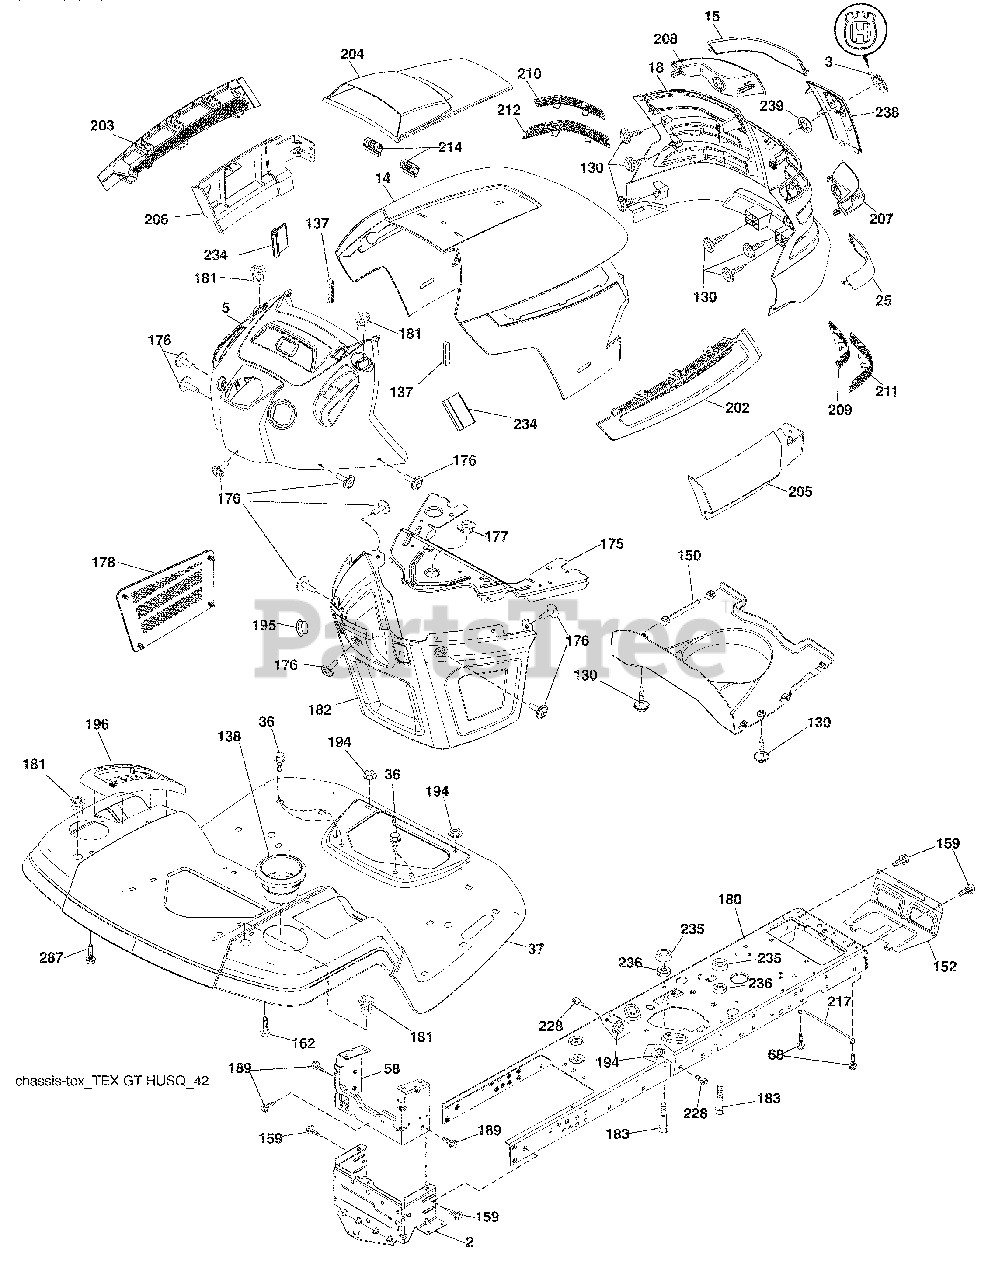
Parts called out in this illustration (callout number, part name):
2	Drawbar Lower
3	Logo
14	Hood
18	Grille/Lens Asm.
36	Screw 5/16-18 x 3/4
37	Fender
58	Drawbar Upper 2PC Sml. Fender
68	Screw Thdrol 5/16-18 x 1/2
130	Screw #10 x 0.750
137	Bumper Dash
138	Cupholder
152	Shield Browning
159	Screw Hex THDROL 3/8-16 x 3/4
175	Crossmember
176	Screw 10-24 x 5/8
177	Bushing Steering
178	Cargo Net Asm.
180	Chassis
181	Bushing Mtg. Fender Crgo
182	Dash Lower
183	Bolt Fin Hex 5/16-18 unc x 1-1/4
189	Screw 5/16-18 x 3/4
194	Nut Lock Hex Flange 5/16-18
195	Plug Hole Dash Lower
196	Console Asm. Deck Lift
202	Vent Side Hood RH
203	Vent Side Hood LH
204	Vent Top Hood
205	Skirt Hood Side RH
206	Skirt Hood Side LH
209	Insert Hex Top RH
210	Insert Hex Top LH
211	Insert Hex Bottom RH
212	Insert Hex Bottom LH
213	Bolt 5/16-18 x 3/4
214	Clip Retainer Tinner
228	Stud Fastner
234	Bumper Hood
235	Spacer Fender
236	Nut Lock 5/16-18 unc
287	Screw 1/4-20 x 3/8
